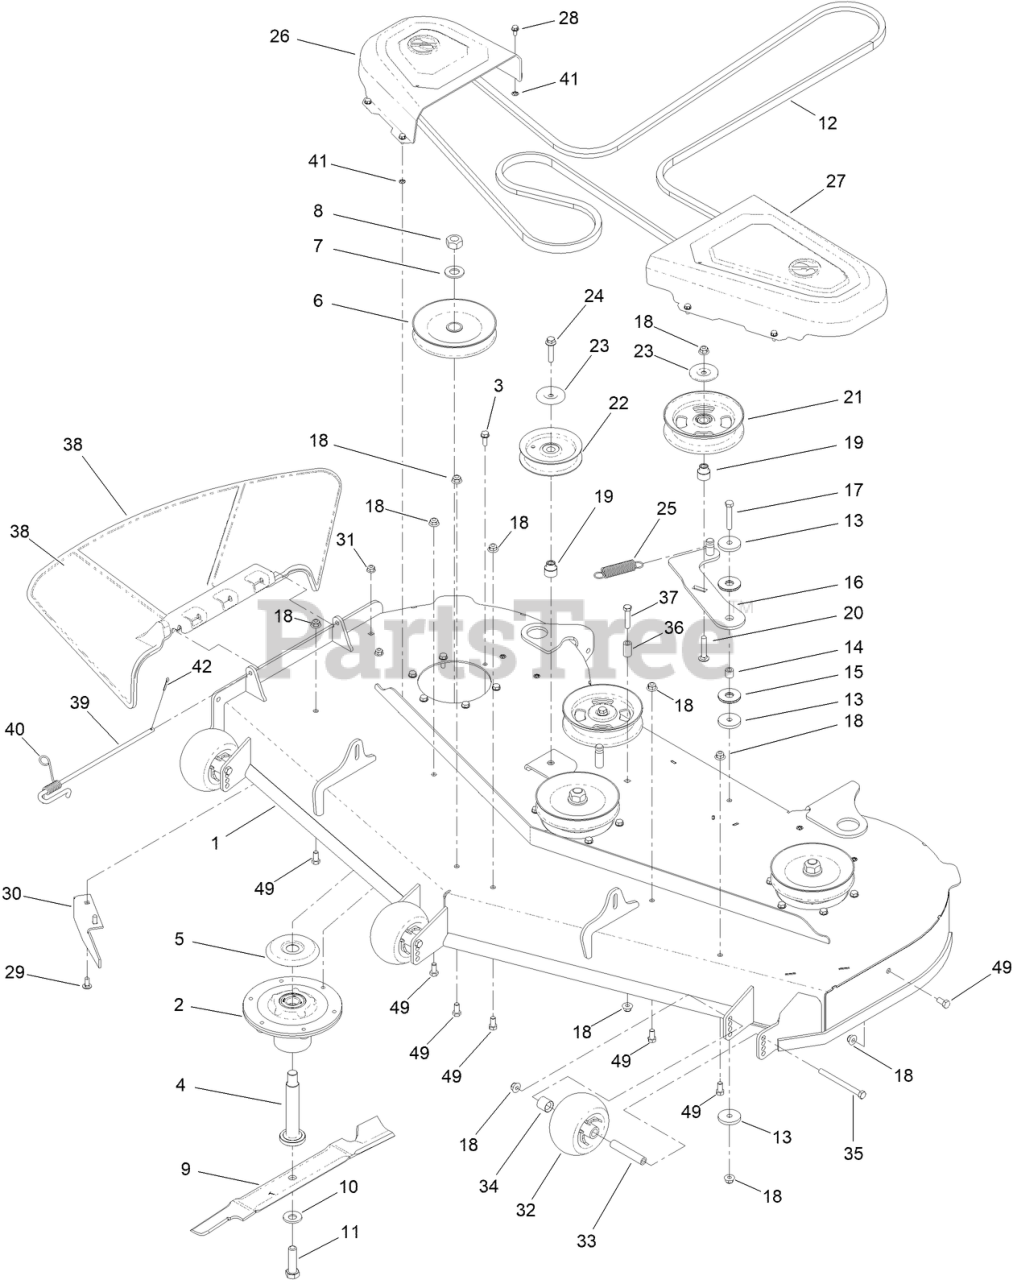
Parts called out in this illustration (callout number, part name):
1	DECK ASM-60"
2	SPINDLE ASM
3	SCREW-TAPTITE
4	SHAFT-SPINDLE
5	SHIELD-BEARING
6	PULLEY
7	WASHER
8	NUT-HEX
9	BLADE - HIGH FLOW, 20.50 IN.
10	WASHER-BELLEVILLE
11	SCREW-BLADE
12	BELT-V
13	WASHER-PLAIN
14	BUSHING-IDLER
15	WASHER-FRICTION, COMPOSITE
16	IDLER ARM ASM
17	SCREW-HH
18	NUT-HF, NI
19	BUSHING-IDLER
20	SCREW-CARR
21	PULLEY-IDLER, FLAT
22	PULLEY-IDLER, FLAT
23	SHIELD-DUST
24	SCREW-HHF
25	SPRING-EXTENSION
26	COVER-BELT, RH
27	COVER-BELT, LH
28	SCREW-HWH
29	SCREW-CARR
30	BAFFLE-CUTOFF
31	NUT-HF, NI
32	ROLLER-SCALP, ANTI
33	TUBE-SPANNER
34	SPACER-AXLE, REAR
35	SCREW-HH
36	SPACER-FENDER
37	SCREW-HH
38	DEFLECTOR-DISCHARGE
39	PIN-CHUTE
40	SPRING-TORSION
41	NUT-RETAINING
42	PIN-COTTER
49	SCREW-HH
